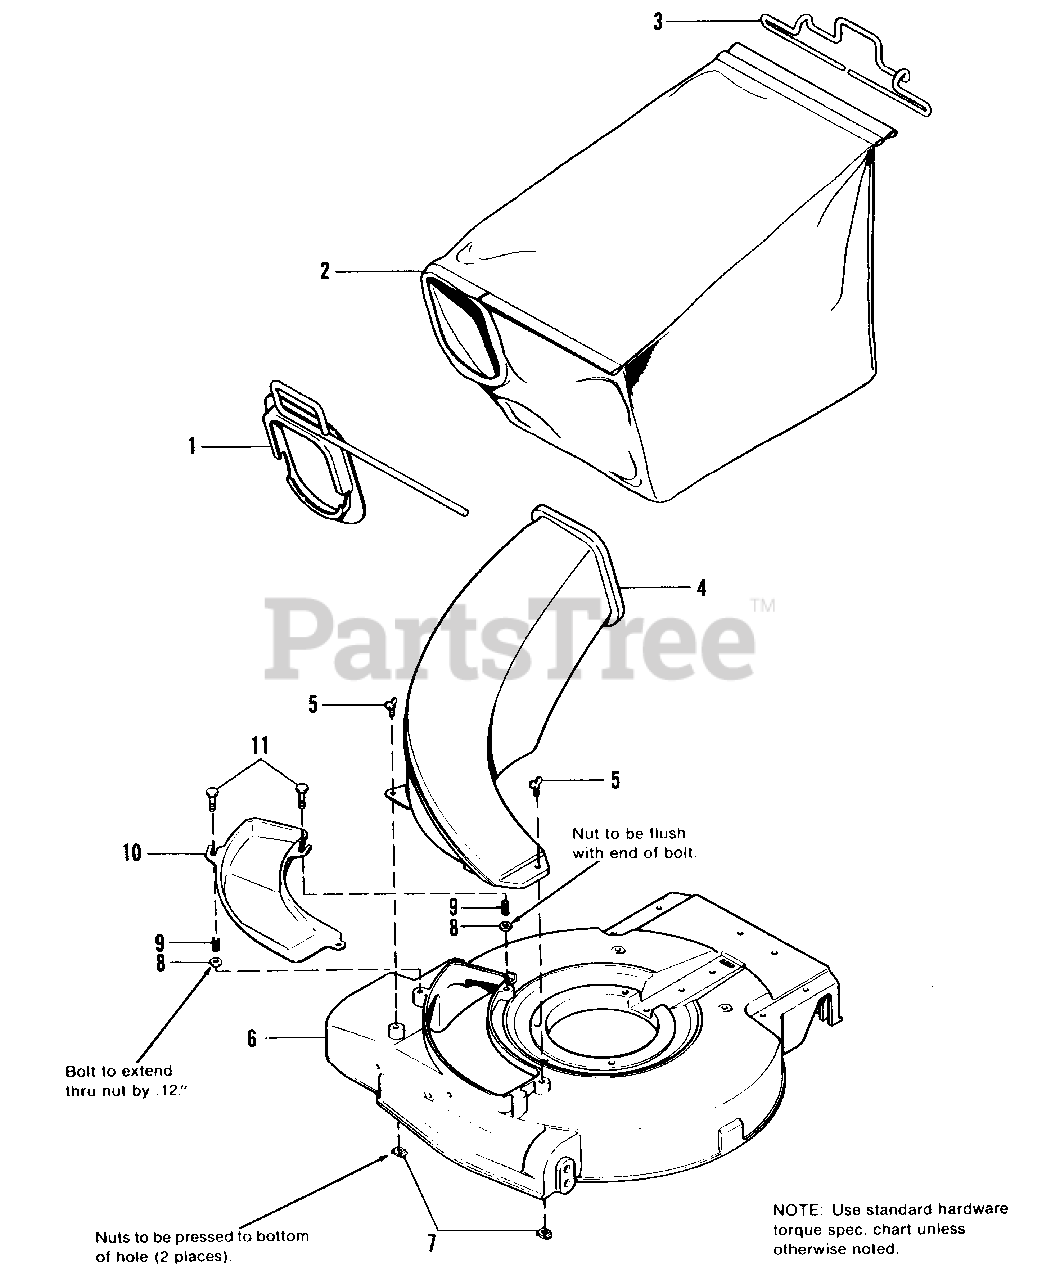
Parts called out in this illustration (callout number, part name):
1	COLLAR ASSY.
2	BAG, Grass
3	SUPPORT, Bag, Rear
4	CHUTE ASSY., Grass
5	SCREW, Thumb, 1/4-20 x 5/8
6	REPLACEMENT KIT, 21" Mower Deck
7	NUT, Tinnerman, 1/4-20
8	LOCKNUT, Hex, 1/4-20
10	PLATE, Cover
11	SCREW, Special
